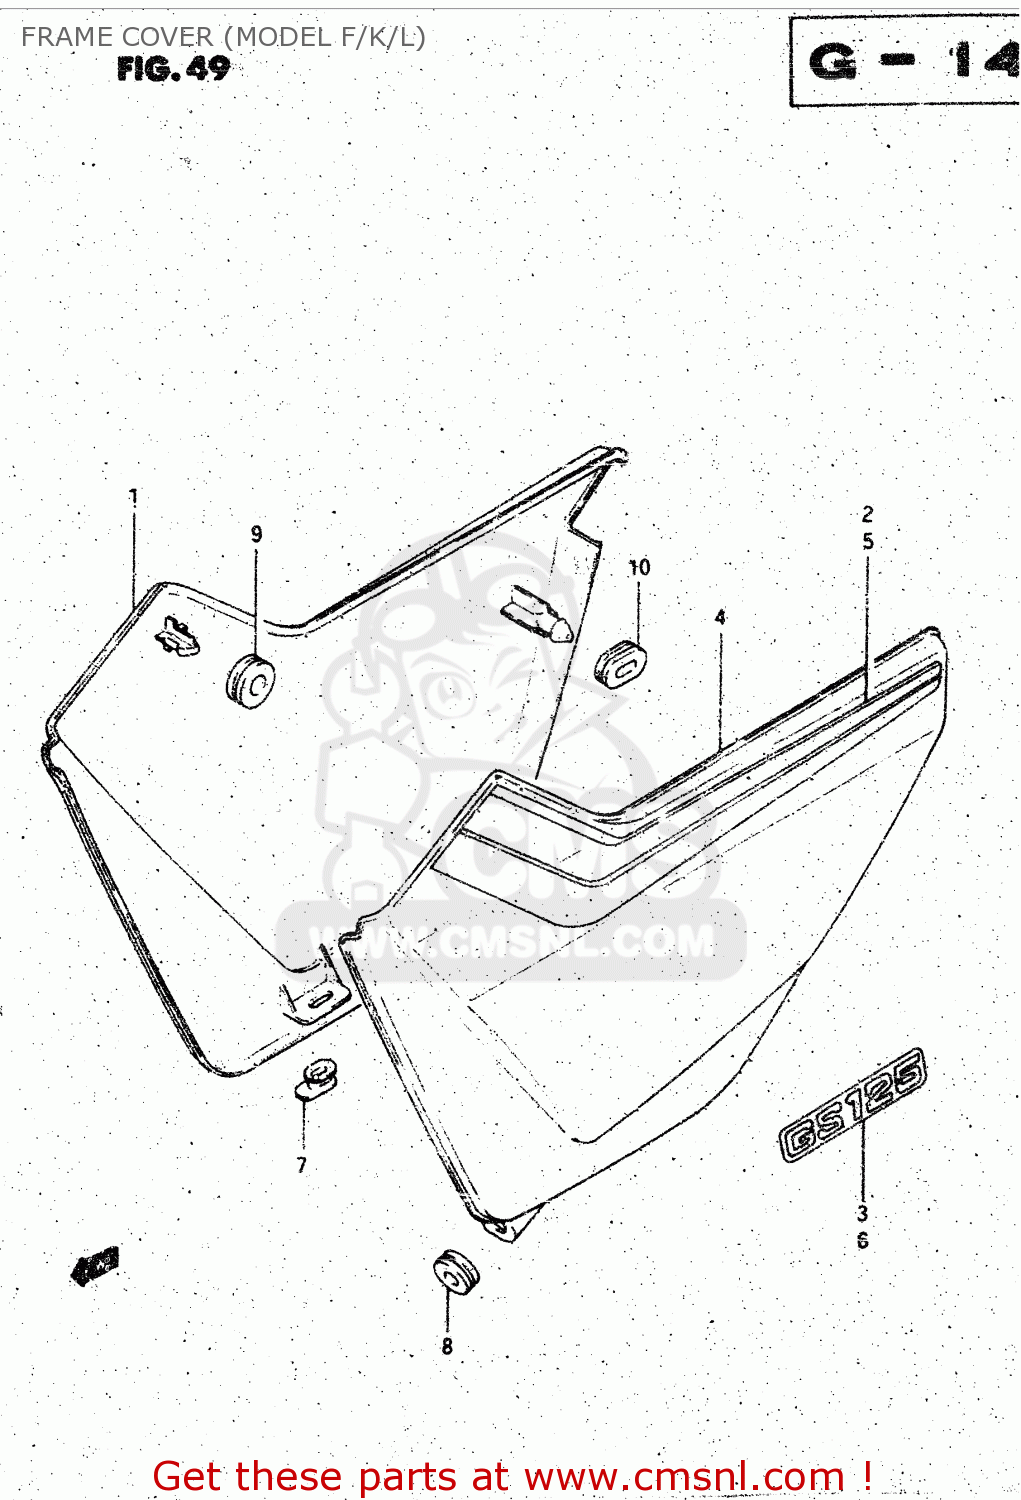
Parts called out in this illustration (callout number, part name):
1	COVER,FRAME,R(RED)
2	TAPE SET, FRAME COVER RH
3	EMBLEM
4	COVER,FRAME,L(RED)
5	TAPE SET, FRAME COVER LH
6	EMBLEM
7	CUSHION
8	CUSHION
9	CUSHION
10	CUSHION
